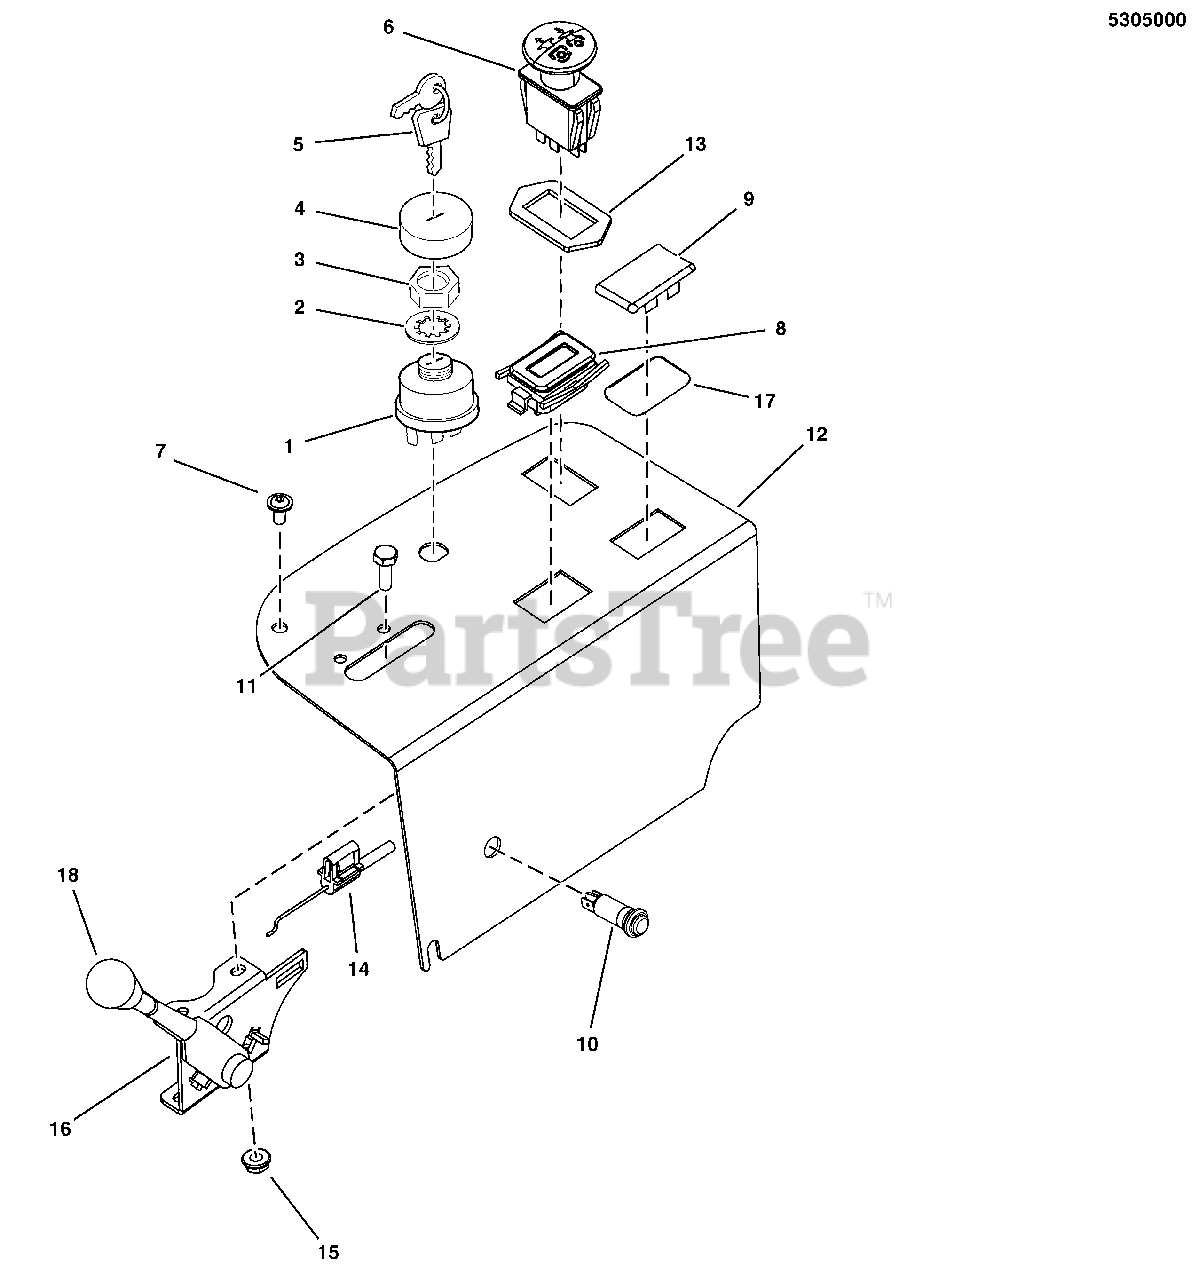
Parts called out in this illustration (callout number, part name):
1	SWITCH ASSEMBLY, Ignition Indak No Keys/Hdwr
2	LOCKWASHER, Internal Tooth, 5/8 Thin
3	NUT, Hex Flange, 5/8-32 IGN SW DIE CAST
4	COVER, Ignition Switch
5	KEYS, Ignition
6	SWITCH, PTO, Push/Pull
7	SCREW, Flange
8	HOUR METER, 2 CHANNEL
9	PLUG, Hole, Electric Lift (Hydro models only)
10	LIGHT, INDICATOR, PANEL, LED, RED
11	SCREW, #10-24 X 3/4", ROUND PHILLIPS
12	PANEL, CONTROL, IS2100Z - BLK
13	RING, SWITCH RETAINER, PTO
14	CABLE, THROTTLE, 47"
15	NUT, Nylock, #10-24
16	LEVER, THROTTLE CONTROL, HEAVY DUTY
17	O-RING, 7/8" ID X 1/16" W
18	THROTTLE CONTROL HANDLE/KNOB
